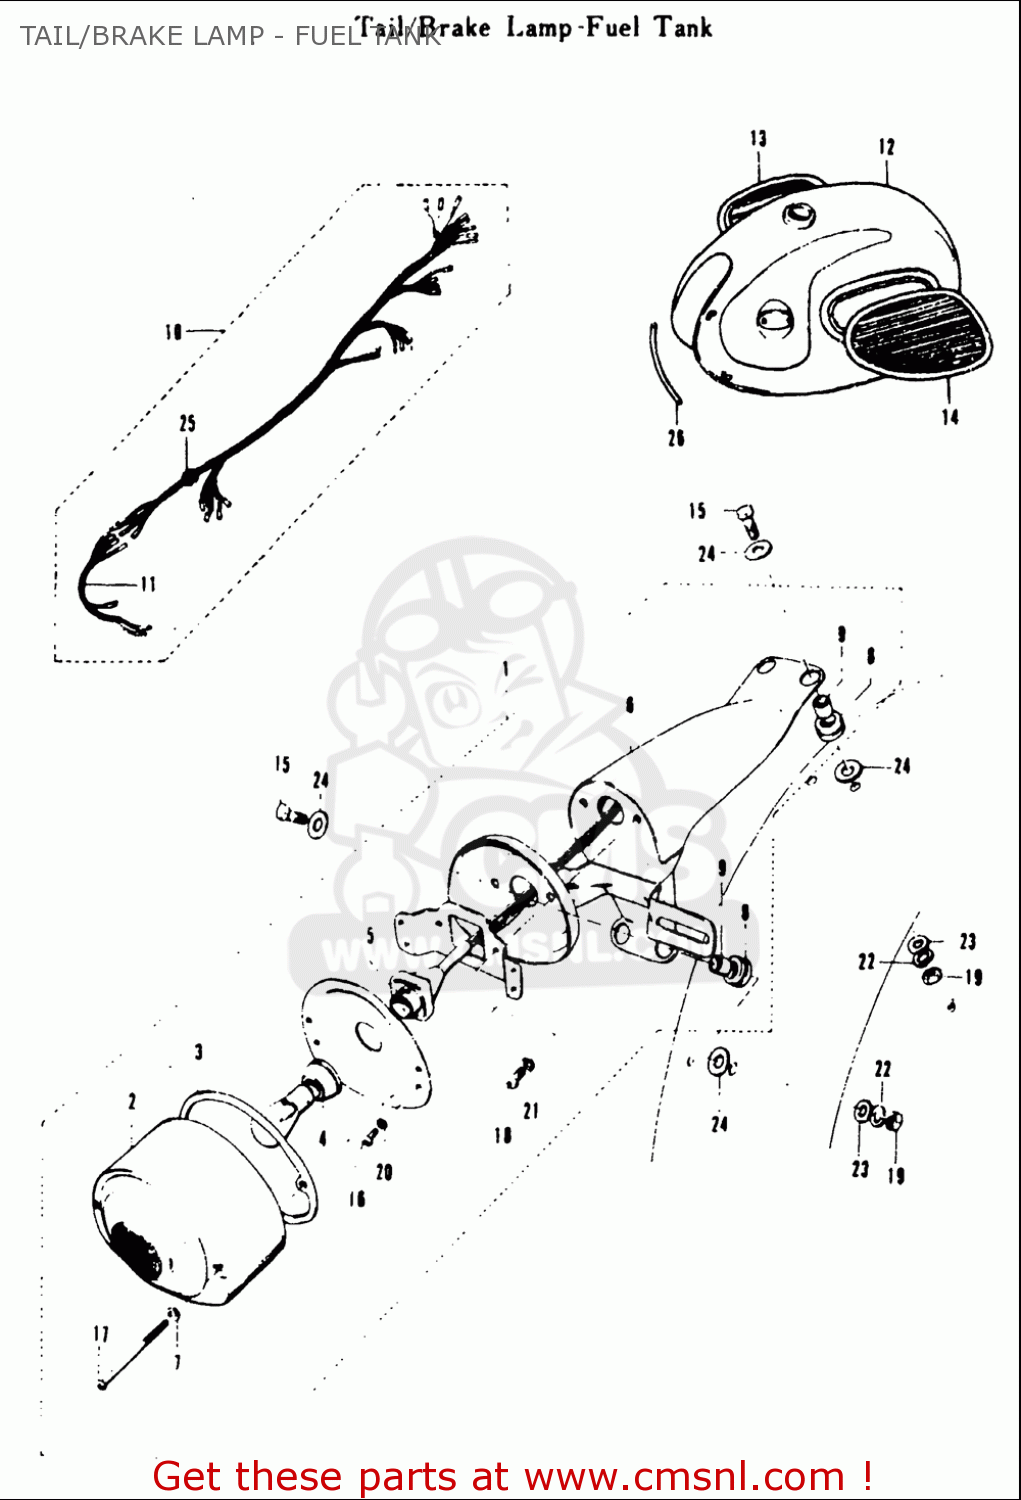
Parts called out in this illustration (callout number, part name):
2	LENS,RR COMBINATION LAMP
8	CUSHION
9	SPACER
19	NUT
20	WASHER,LOCK
21	WASHER,LOCK
22	WASHER,LOCK
23	WASHER
24	WASHER(6.5X20X1.6)
